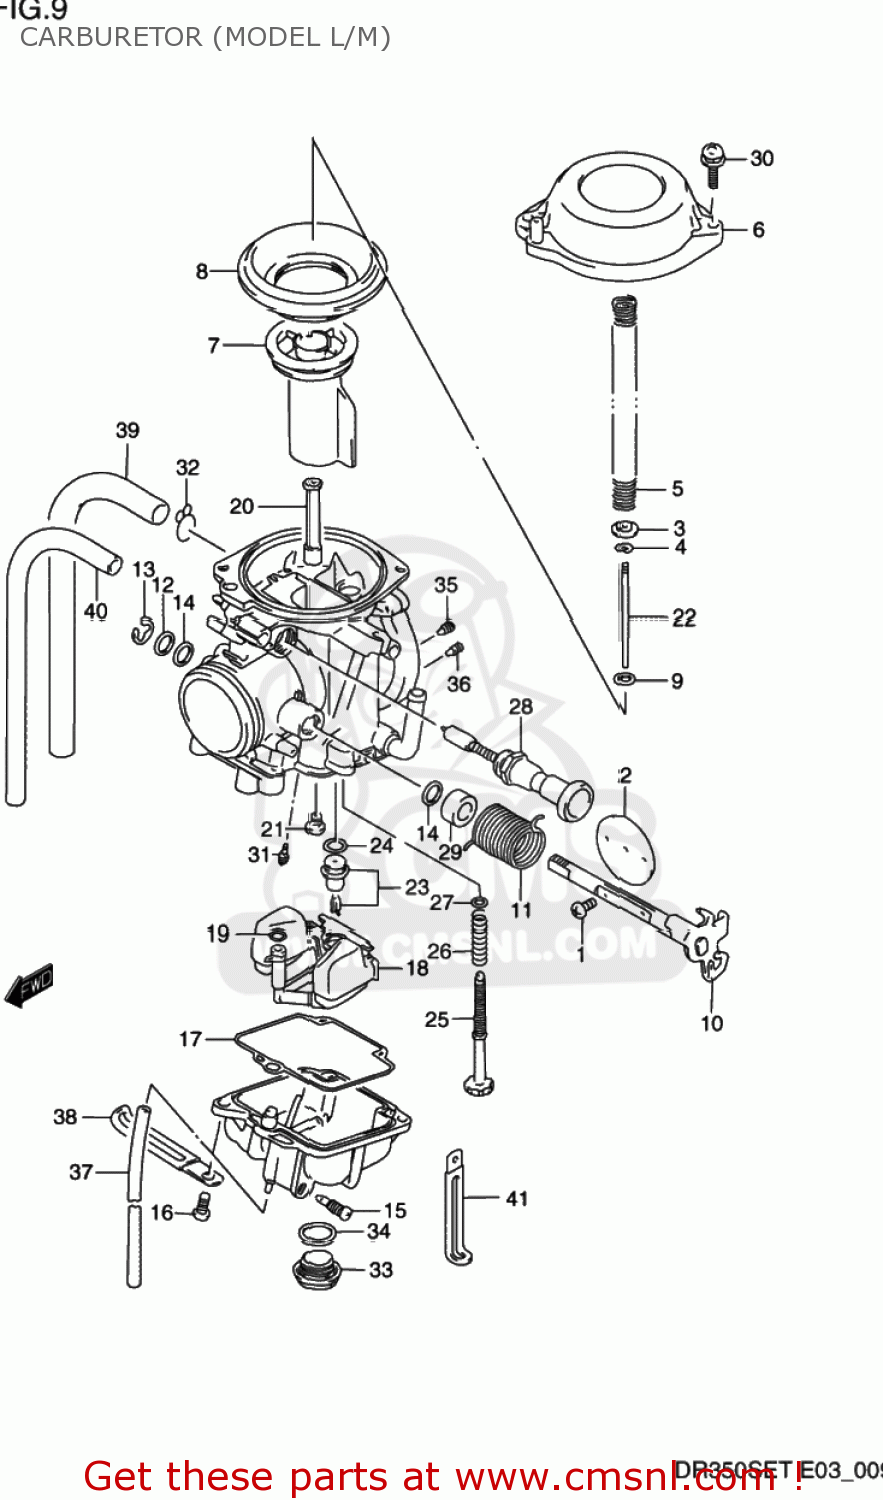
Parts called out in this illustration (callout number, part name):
1	SCREW
2	VALVE,THROTTLE (115)
3	RING
4	E RING
5	SPRING
6	COVER,DIAPHRAGM
7	VALVE PISTON
8	DIAPHRAGM
9	RING
10	SHAFT ASSEMBLY
11	SPRING
12	GASKET,THROTTLE SHAFT (NAS)
13	E RING
14	SEAL
15	PLUG,DRAIN
16	SCREW
17	GASKET,FLOAT CHAMBER (NAS)
18	FLOAT ASSY
19	O RING
20	JET,NEEDLE (O-6)
21	JET,MAIN(135)
22	NEEDLE,JET
23	VALVE ASSEMBLY,NEEDLE
24	O-RING,NEEDLE VALVE
25	SCREW,ADJUSTER
26	SPRING
27	WASHER
28	PLUNGER ASSY
29	RING
30	SCREW
31	JET,PILOT(37.5)
32	CLIP
33	SCREW,GUIDE
34	O RING,DRAIN PLUG
35	JET,AIR(1.3)
36	JET,AIR(0.6)
37	HOSE
38	CLIP
39	HOSE
40	HOSE
41	CLAMP L:35
